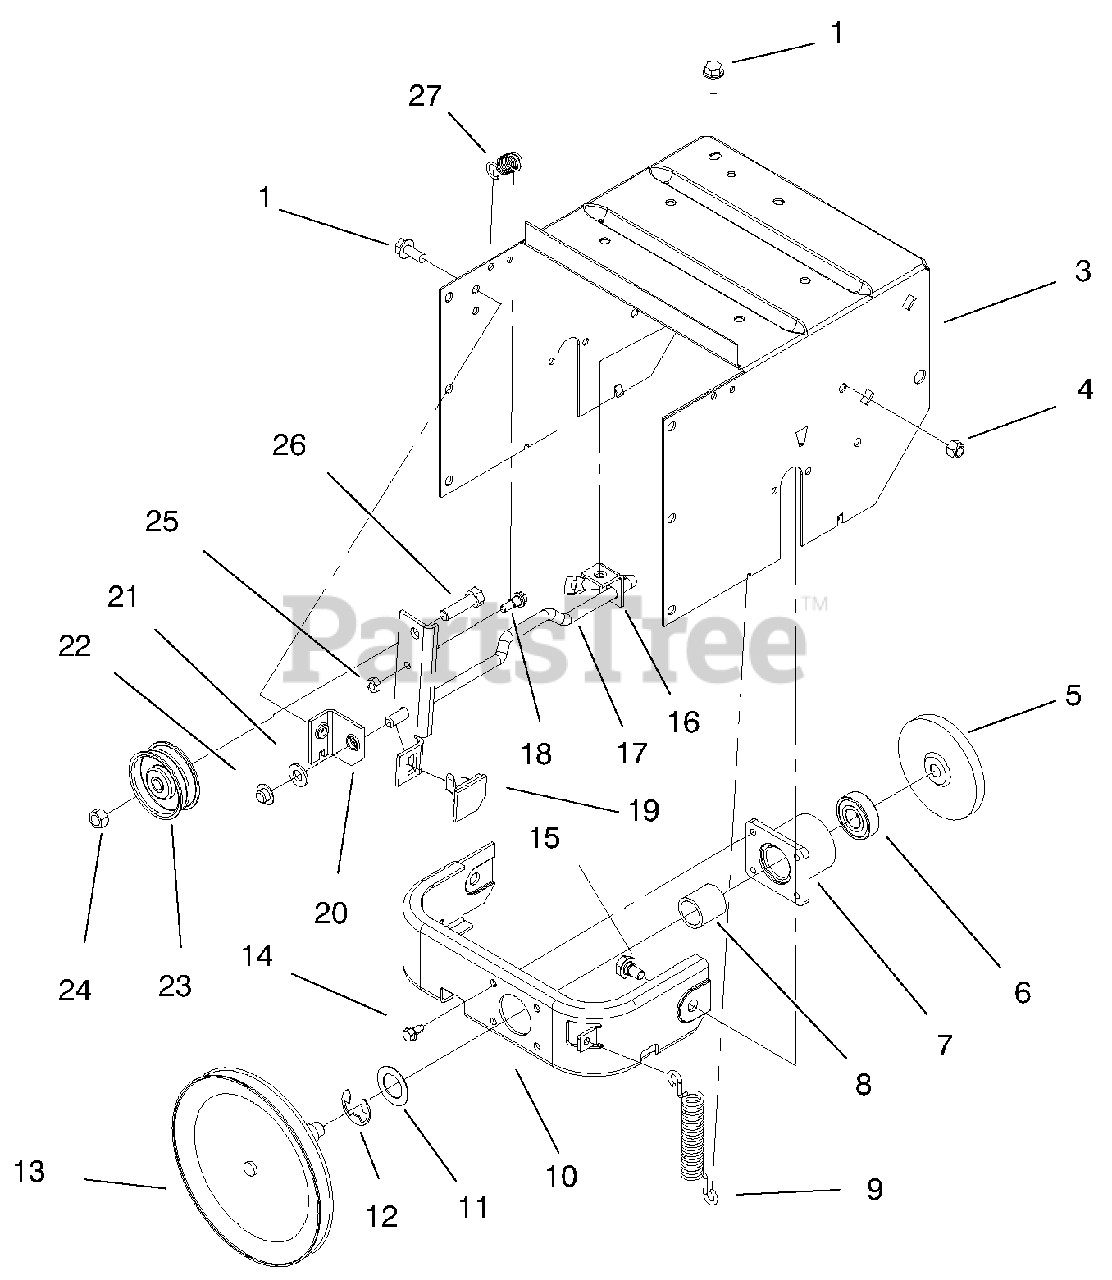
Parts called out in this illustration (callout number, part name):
3	Frame-Traction
4	Nut-Lock
5	Plate-Friction
6	Bearing-Ball
7	Hub-Frame, Traction
9	Spring-Plate,Friction
10	Frame-Front
11	Bearing-Thrust
12	Ring-Snap
13	Pulley & Drive ASM
15	Bolt-Shoulder
16	Bracket-Mount Clutch, Rear
17	Rod-Clutch, Auger
18	Bolt-Shoulder
19	Pad-Brake
20	Bracket-Mount Clutch, Front
21	Washer-Flat
22	Retainer-Push On
23	Pulley-Idler
24	Nut-Lock Ni
25	Nut-Lock Ni
26	Screw-HH
